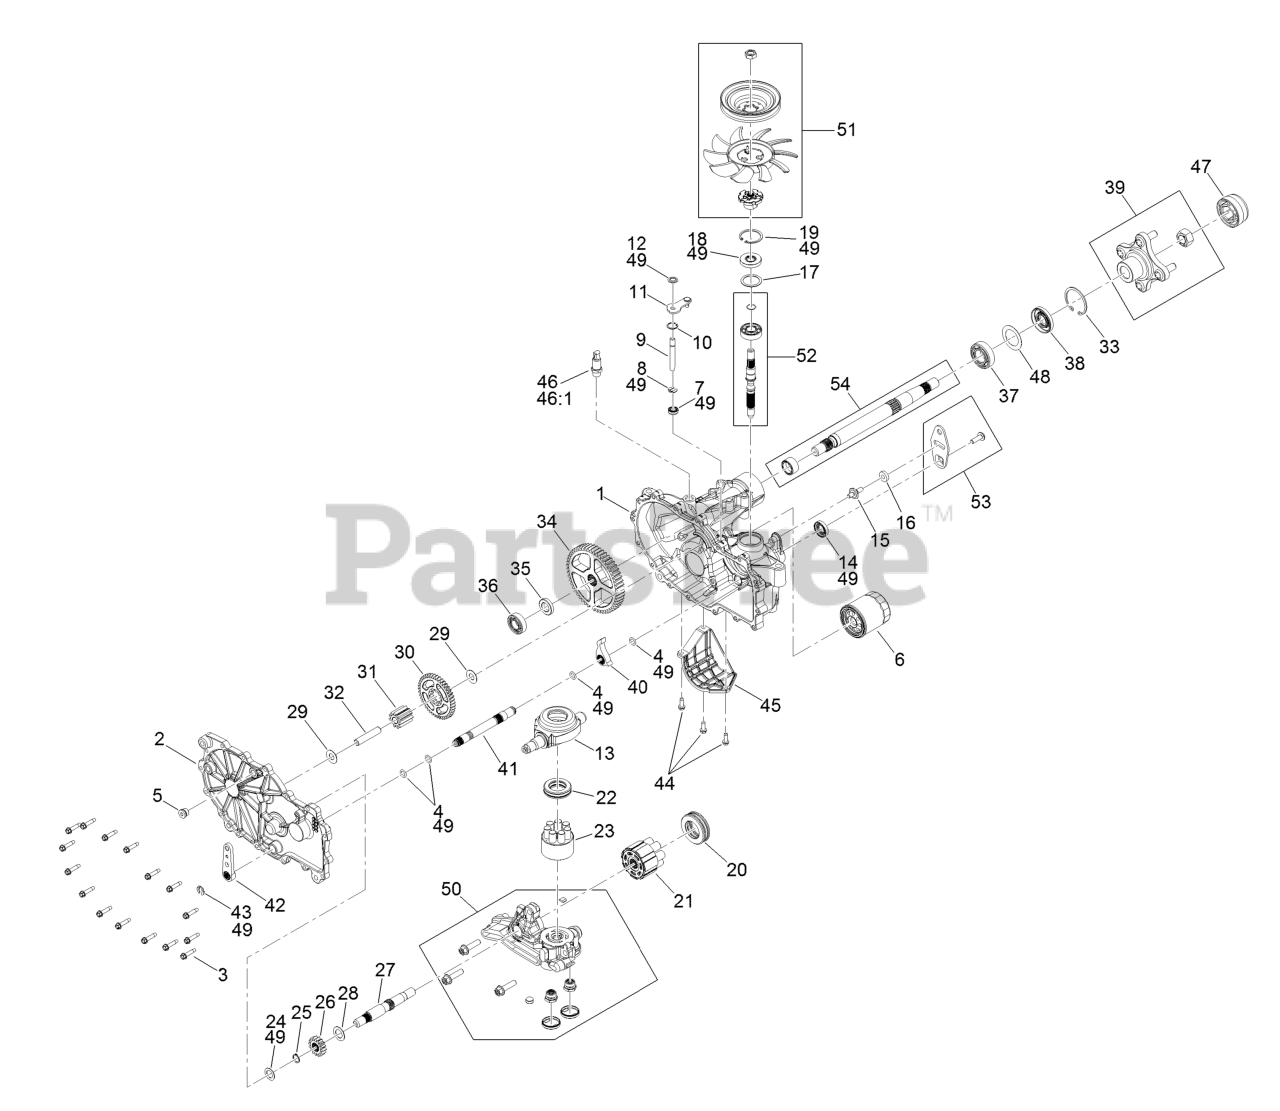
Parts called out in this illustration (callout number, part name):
1	MAIN HOUSING KIT
2	LH SIDE COVER KIT
3	SCREW-HHF
5	PLUG-THREAD, STRAIGHT
6	ELEMENT-OIL FILTER, HYD
7	SEAL-LIP
8	RING-RETAINING, EXTERNAL
9	ROD-BYPASS
10	RING-RETAINING, INTERNAL
11	ARM-BYPASS
12	RING-RETAINING, EXTERNAL
13	SWASHPLATE-TRUNNION
14	SEAL-LIP
16	PUCK-FRICTION
18	SEAL-LIP
19	RING-RETAINING
20	BEARING-THRUST
21	MOTOR CYLINDER BLOCK KIT
22	BEARING-THRUST
23	PUMP BLOCK ASM
24	WASHER-FLAT
25	RING-RETAINING
26	GEAR-16T
27	SHAFT-MOTOR
30	GEAR-43T
31	GEAR-11T
32	PIN-JACKSHAFT
33	RING-RETAINING
34	GEAR-54T
36	BEARING-BALL
37	BEARING-BALL
39	HUB KIT
40	PAWL-BRAKE
41	SHAFT-BRAKE, INBOARD
42	HANDLE-BRAKE
43	RING-RETAINING, EXT
45	GUARD-FILTER, LH
46	ADAPTER-STRAIGHT
46:1	O-RING
47	COVER-NUT, AXLE
49	SEAL KIT
50	CENTER SECTION KIT
51	FAN PULLEY KIT
52	INPUT SHAFT KIT
53	CONTROL ARM KIT
54	AXLE SHAFT KIT
